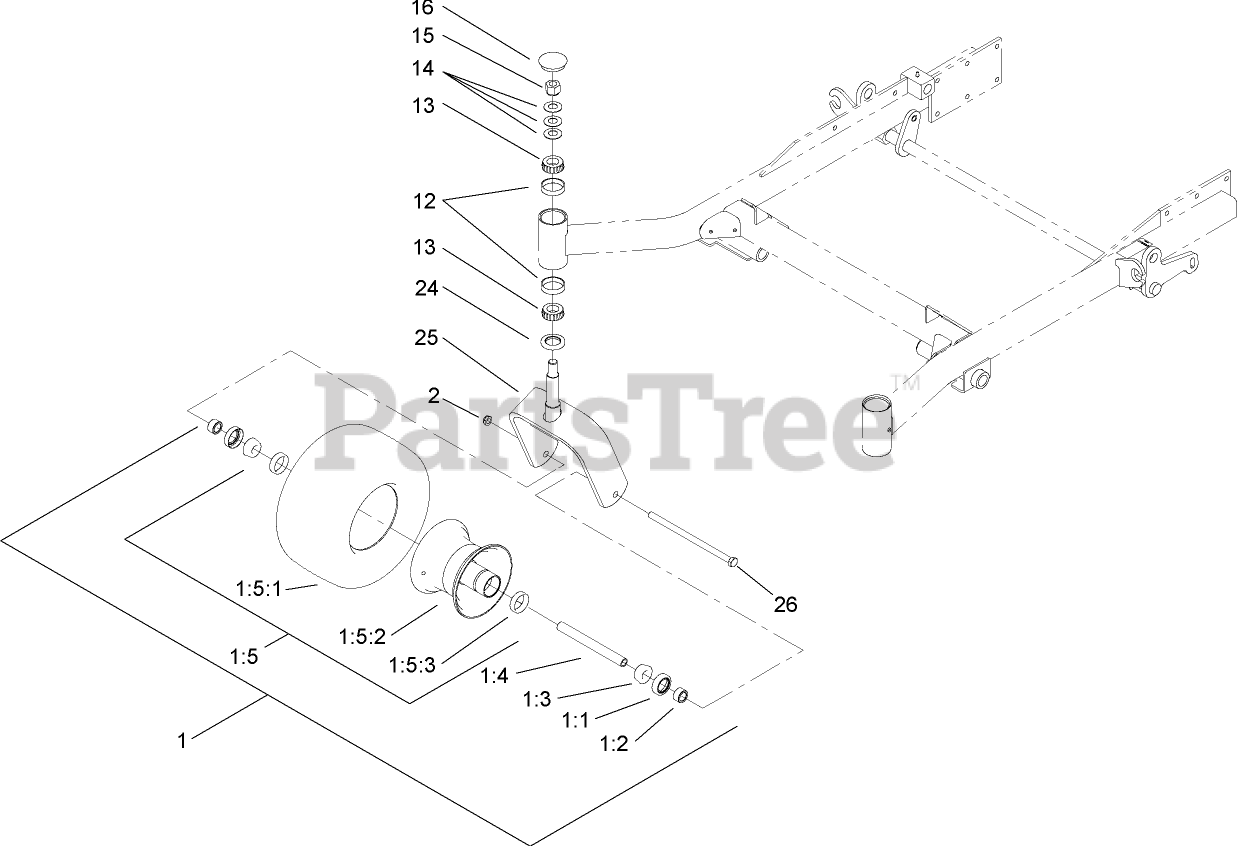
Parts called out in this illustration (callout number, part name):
1	CASTER WHEEL ASM
1:1	SEAL-BEARING
1:2	SPACER-BEARING
1:3	BEARING-CONE, TAPER
1:4	SPACER-CASTER, FRONT
1:5	WHEEL AND TIRE ASM
1:5:3	BEARING-CUP
2	NUT-LOCK, NI
12	BEARING-CUP, TAPERED
13	BEARING-CONE, TAPERED
14	WASHER-BELLVILLE
15	NUT-LOCK, NI
16	CAP-GREASE
24	SEAL-GREASE
25	CASTER-FORK
26	Screw-HH
